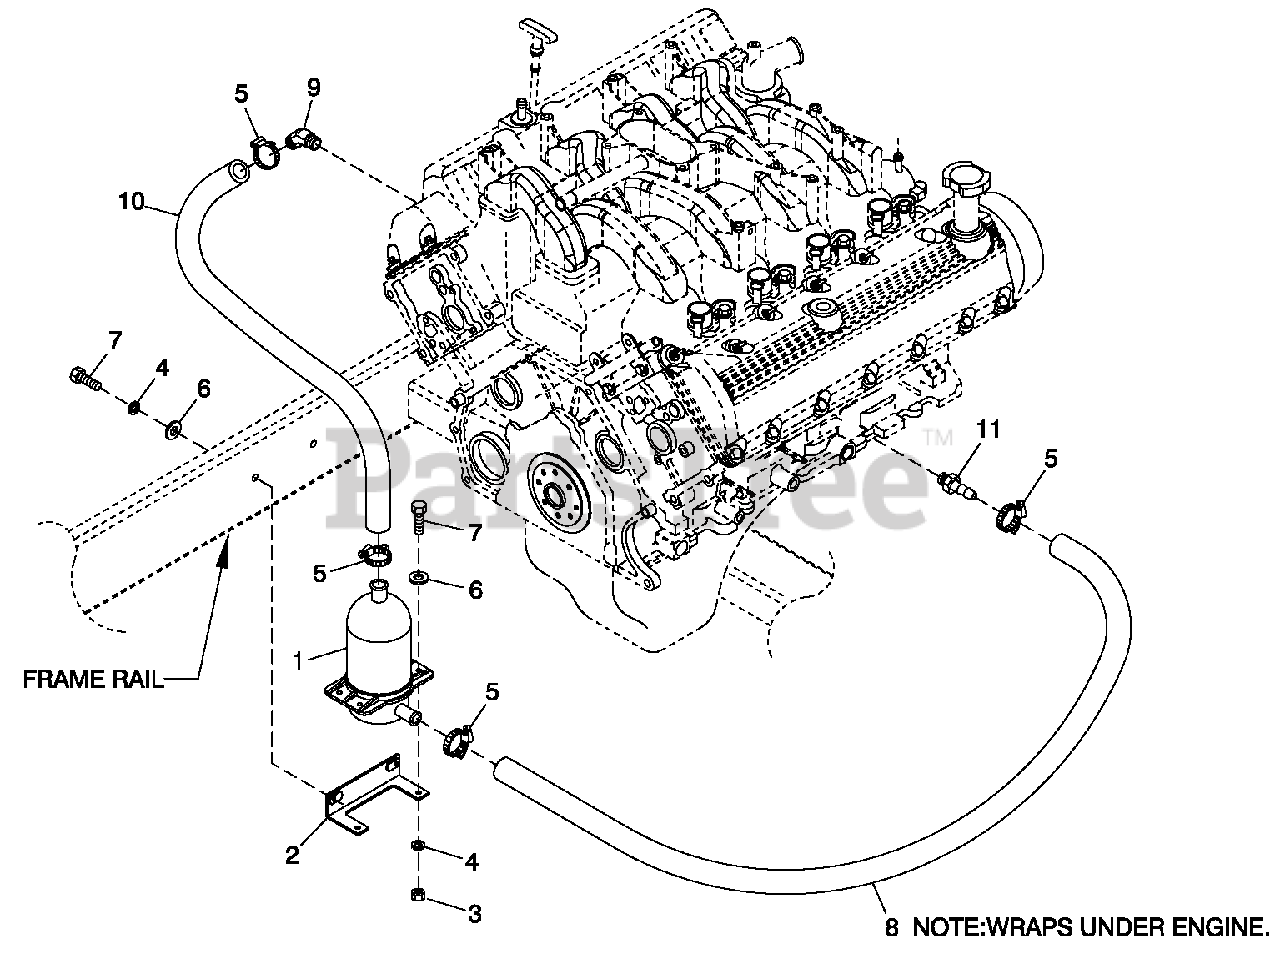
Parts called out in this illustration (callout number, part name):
1	HEATER BLOCK 2000W 240V
2	BRACKET HEATER W/WELDNUTS
3	NUT HEX M6 X 1.0 G8 YEL CHR
4	WASHER LOCK M6-1/4
5	CLAMP HOSE #8 .53-1.00
6	WASHER FLAT 1/4-M6 ZINC
7	SCREW HHC M6-1.0 X 20 G8.8
8	HOSE COOL 5/8 ID 20R3 (24" LG)
9	BARBED EL 45 3/8 NPT X 5/8 OD
10	HOSE PREFORMED BLOCK HEATER
11	BARBED STR 3/8 NPT X 5/8
